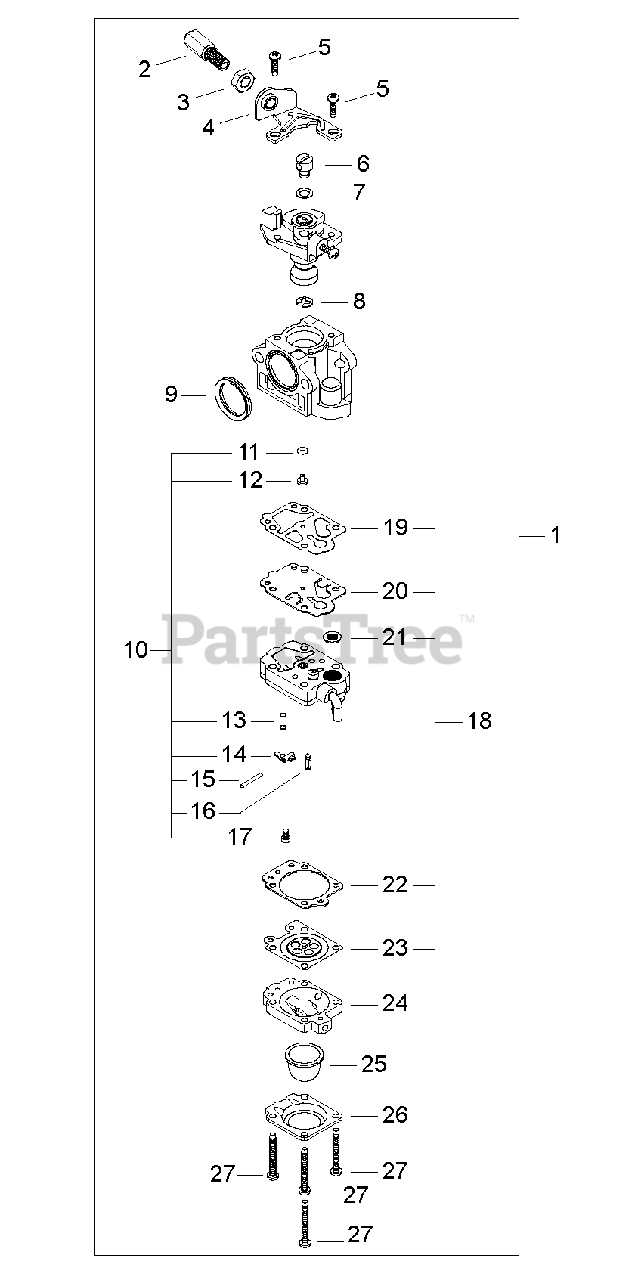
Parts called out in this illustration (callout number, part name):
1	CARBURETOR
2	ADJUSTER, THROTTLE CABLE
3	NUT, ADJUSTER LOCK M7
4	BRACKET, THROTTLE CABLE
5	SCREW
6	SWIVEL
7	WASHER
8	E-RING
9	RING, PACKING
10	VALVE KIT, INLET NEEDLE
11	O-RING
12	JET, MAIN #58.5 (STD)
13	SPRING, METERING LEVER
14	LEVER, METERING
15	PIN, METERING LEVER
16	VALVE, INLET NEEDLE
17	SCREW
18	GASKET / DIAPHRAGM KIT
19	GASKET, PUMP
20	DIAPHRAGM, PUMP
21	SCREEN, FUEL INLET
22	GASKET, METERING DIAPHRAGM
23	DIAPHRAGM, METERING
24	BODY ASSY, PURGE
25	BULB, PURGE
26	RETAINER, PURGE BULB
27	SCREW
